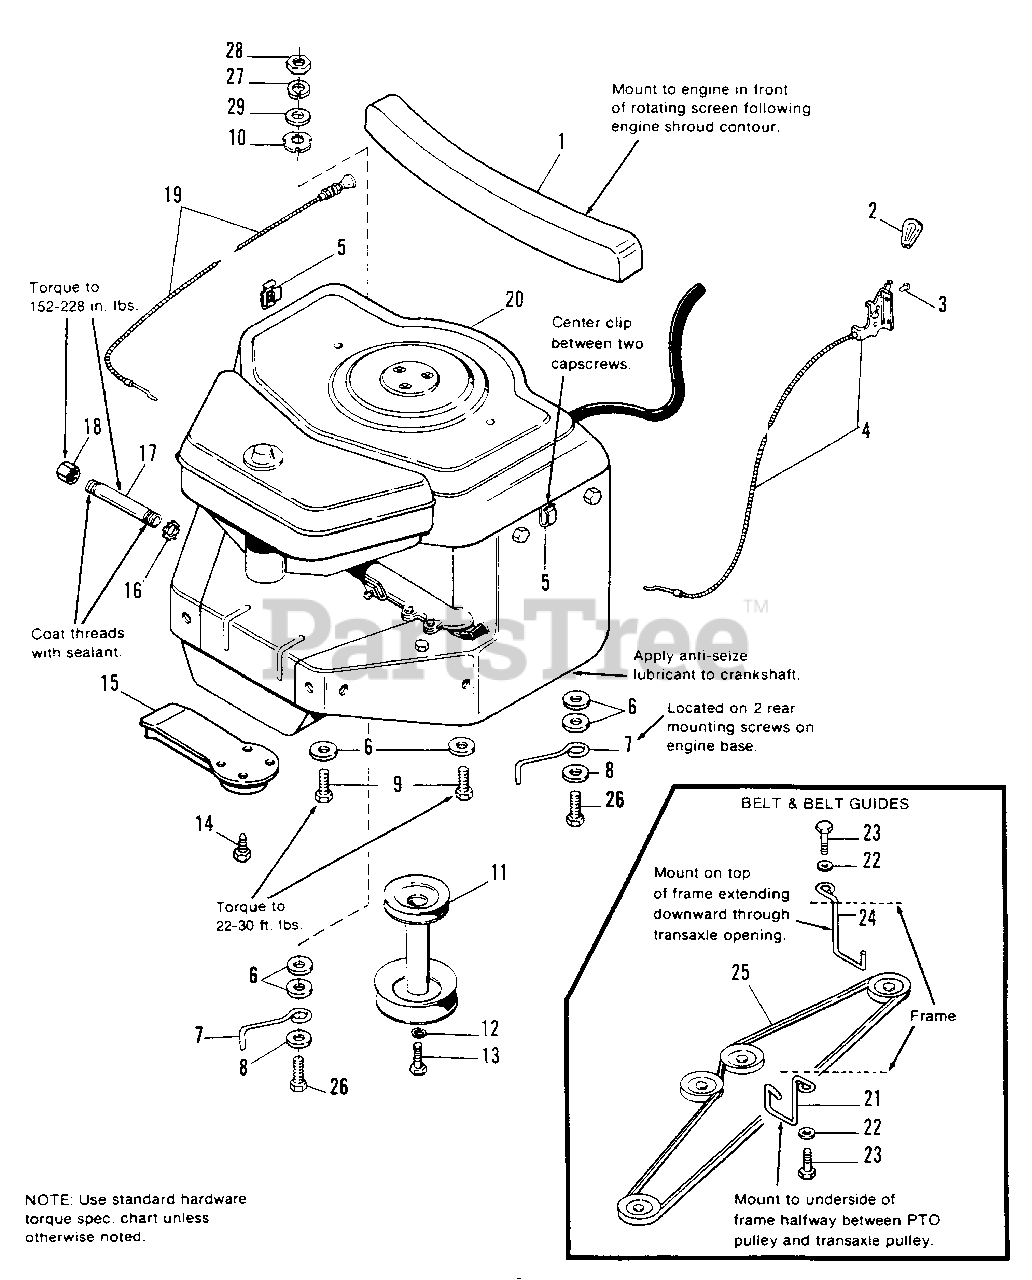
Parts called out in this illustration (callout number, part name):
1	BAFFLE, Engine Rear
2	KNOB, Throttle
4	CONTROL ASSY., Throttle
6	WASHER, 3/8
7	BELT Stop
8	WASHER, 3/8
9	SCREW, Taptite, 3/8-16 x 1-1/2
10	LOCKWASHER, Pyramidal Type, 3/8
11	PULLEY ASSY., Engine
12	LOCKWASHER, 7/16
13	CAPSCREW, Hex, 5/16-20 x 1-1/4
14	SCREW, Hex, Thd. Cutting, #8-32 x 3/8
15	EXTENSION ASSY., Muffler
16	LOCKNUT, Conduit
17	OIL DRAIN
19	CABLE, Choke
20	ENGINE ASSY., Briggs & Stratton 12.5 HP
20	ENGINE ASSY., Briggs & Stratton 16 HP
21	GUIDE, Belt
23	SCREW, Taptite, 5/16-18 x 5/8
24	GUIDE, Belt
25	BELT, "V", Transmission Drive
26	SCREW, Taptite, 3/8-16 x 2-1/2
27	LOCKWASHER, 3/8 (Zinc Pltd.)
28	NUT, Hex, Full, 3/8-16 (Zinc Pltd.)
29	WASHER, 3/8 (Zinc Pltd.)
